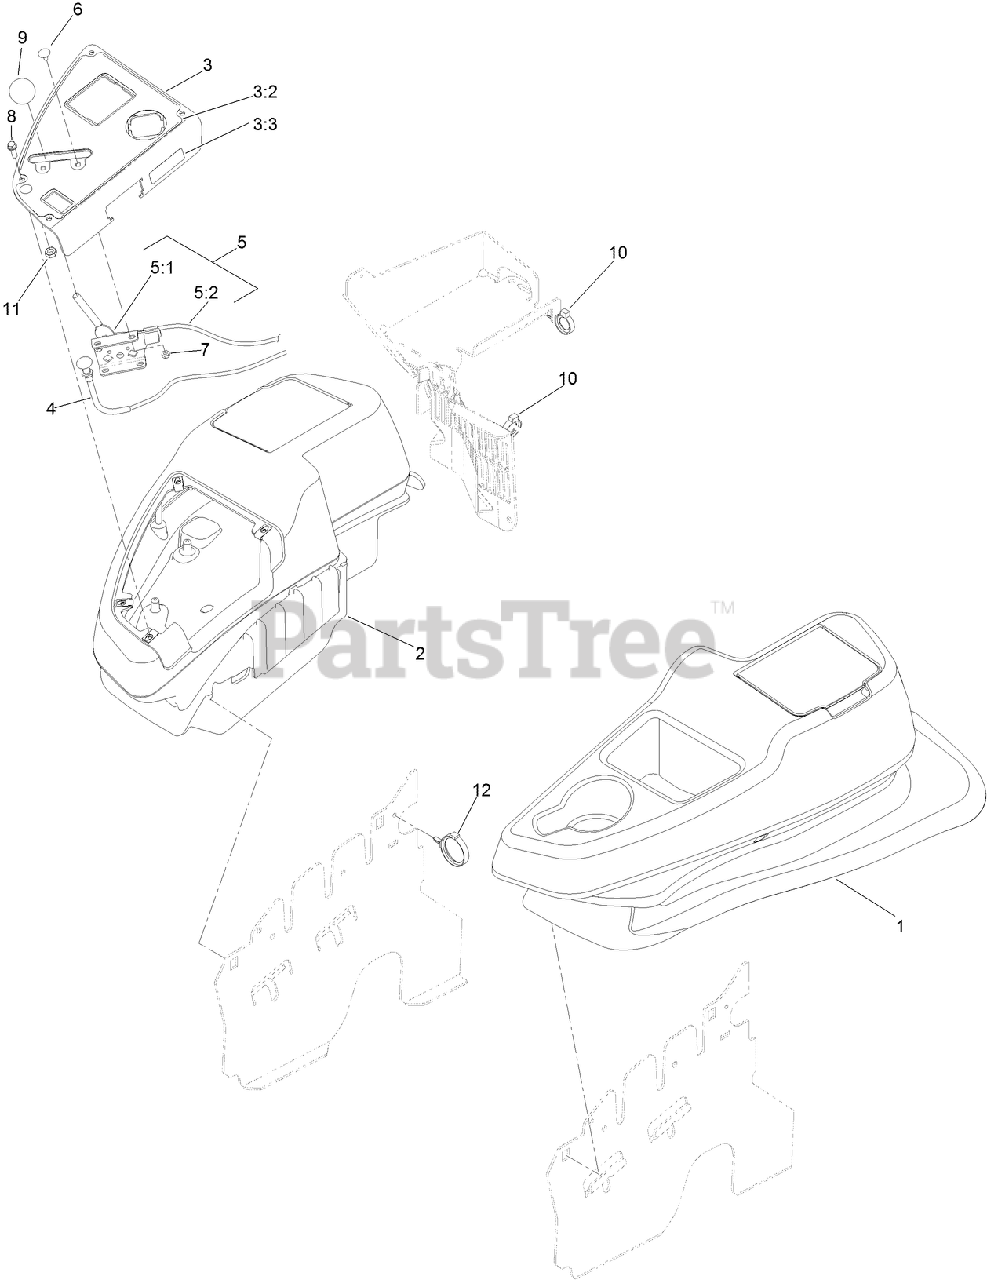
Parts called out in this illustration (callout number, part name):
1	LH CONSOLE ASM
2	RH CONSOLE ASM
3	CONTROL PANEL ASM
3:2	DECAL-PANEL, CONTROL
3:3	DECAL-FUSES
4	CONTROL-CHOKE
5	THROTTLE CONTROL ASM
5:1	LEVER-THROTTLE
5:2	CABLE-THROTTLE
6	BOLT-CARR
7	NUT-LOCK, NI
8	SCREW-HWH
9	KNOB-BALL
10	CLAMP-HOSE
11	NUT-HJ
12	CLAMP-HARNESS
